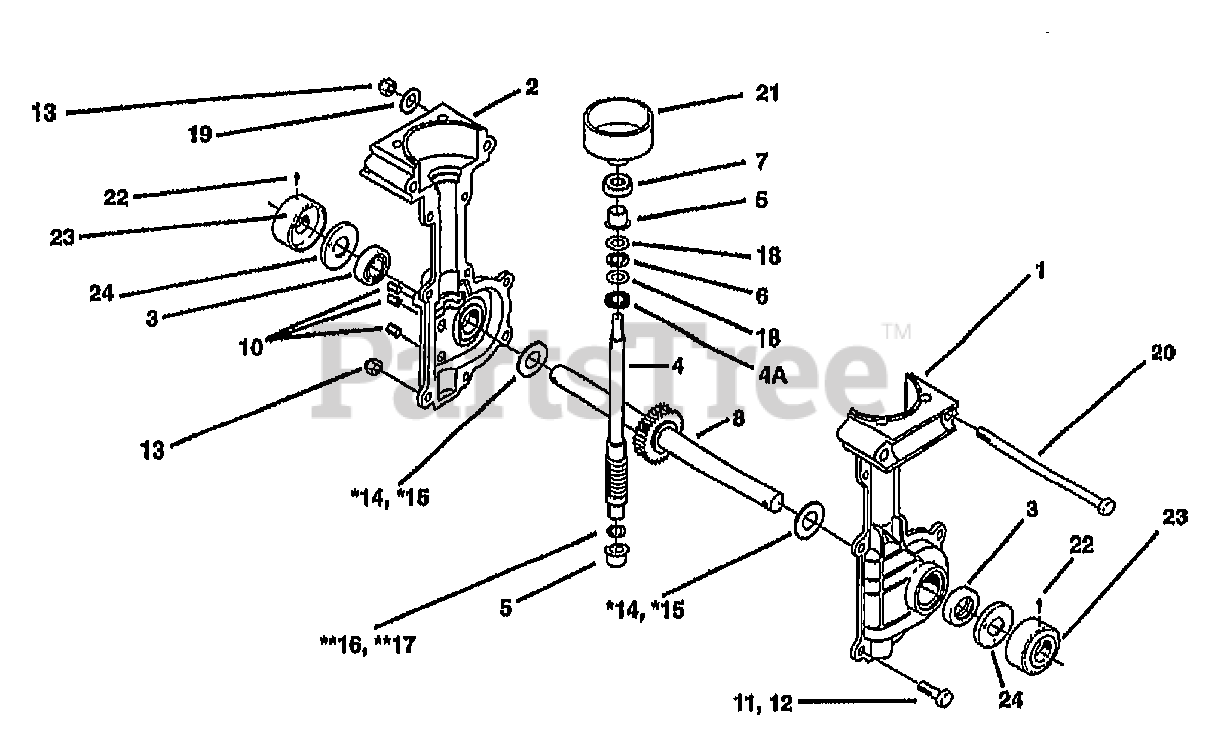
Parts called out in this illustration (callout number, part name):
1	ASSM-TRANS CASE LEFT
2	ASSM-TRANS CASE RIGHT
3	SEAL-PINION SHAFT PT/85030/00
4	SHAFT-WORM PT/85032/00
4A	SEAL-OIL INPUT SHAFT
5	BEARING-INPUT
6	BEARING-THRUST PT/85034/00
7	BEARING-BALL PT/85035/00
8	ASSM-SHAFT OUTPUT AS/85037/00
10	PLUG-PIPE 1/8 NPT
11	SCR-HH 1/4-20 X .875
12	SCR 1/4-20X1.125
13	NUT-LK 1/4-20
14	WASHER-THRUST .775X.05 (.050")
15	WASHER-THRUST .775X.05 (.040")
16	WASHER-THRUST .505X.02 (.020")
17	WASHER-.76X.5X.04 THRUST (.025")
18	WASHER-THRUST .92X.5X.06
19	WASHER-.75X.312X.065 ZP
20	SCR-HH 1/4-20X5
21	ASSM-CLUTCH & DRUM
22	SCR M10-32X.25
23	KIT-DUST CAP
24	WASHER-FELT 1.5X.72X.13
